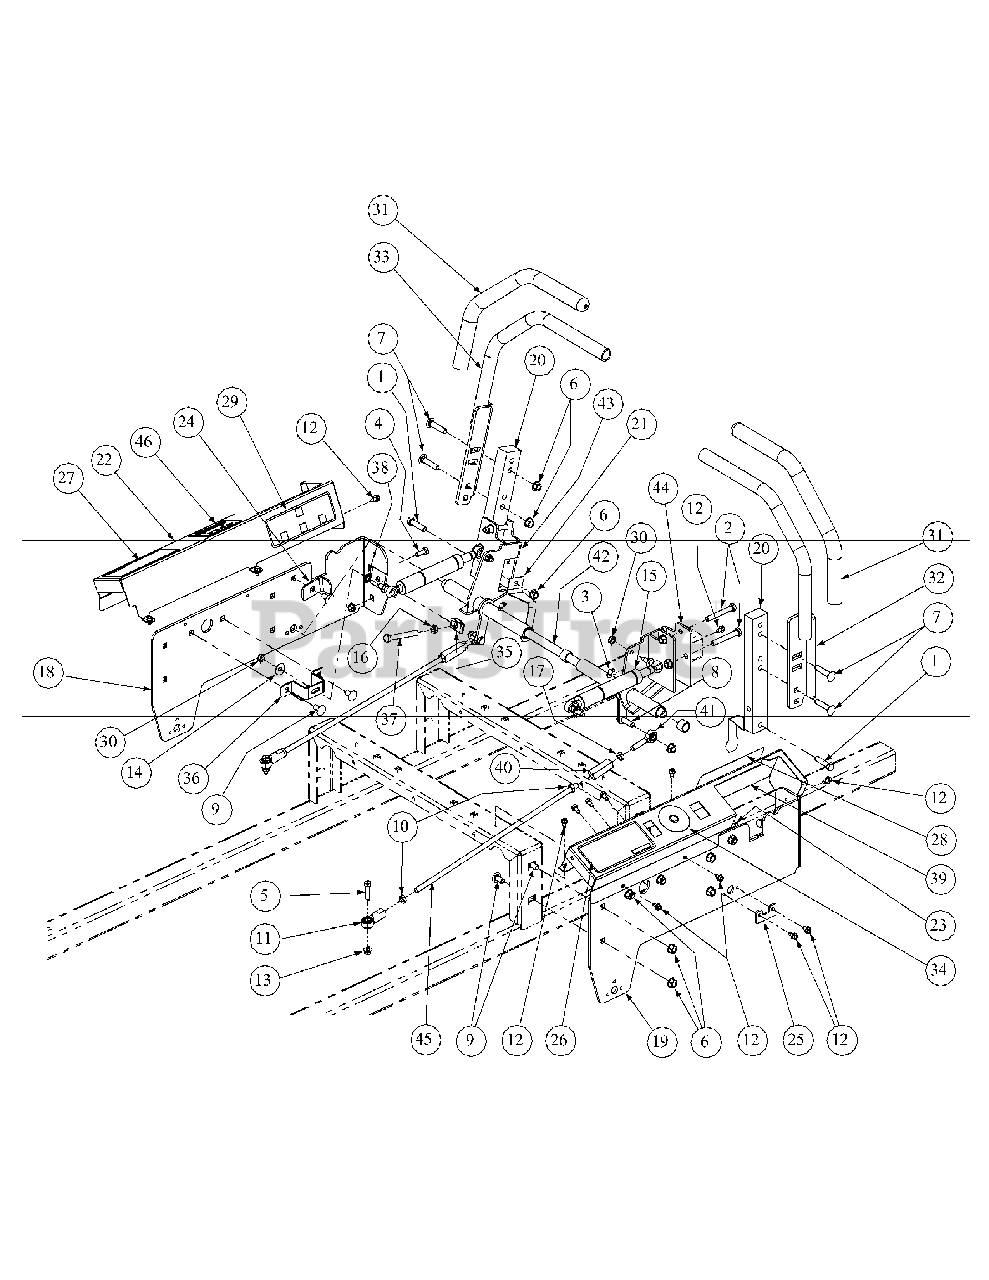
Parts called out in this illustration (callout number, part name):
1	HHCS, 3/8-16, 1.50
2	HHCS, 3/8-16, 2.50
3	Grease Fitting, 1/4-28, 90 degree
4	HHCS, 5/16-18 x 1.0
5	HHCS, 5/16-18 x 1.25
6	Hex Nut, 3/8-16, Lock Flange
7	Hex Carriage Screw, 3/8-16, 1.75
8	HHCS, 3/8-16 x 1.25
9	Carriage Bolt, 3/8-16 x .75
10	Hex Jam Nut, 3/8-24
11	B/Joint, 3/8-24, Right Hand Female
12	Screw, TT, 1/4-20, 0.5, Hex Index Washer
13	Nut, Lock, Hex Flange, 5/16-18
14	Belle Washer, .325 x .930 x .045
15	Cylinder Return to Neutral
16	Nut, 3/8-16, Jam
17	Nut, 3/8-24, Jam, LH Third
18	Side Panel, Control, Left
19	Side Panel, Control, Right
20	Mounting Handle
21	Lever, Safety Switch
22	Control Panel, LH
25	Holder Shaft, Park Brake
26	Decal , Right Hand Console
27	Decal, Left Hand Console
28	Decal Right Hand Control
29	Decal, Left Hand Control
30	Nut, Hex, Center Lock, M8
31	Grip, 1.0
32	Lapbar, Weldment, Right Handle
33	Lapbar, Weldment, Left Handle
34	Label, Ignition, 2.5 Diameter
35	U-Nut, 3/8-16, .75
36	Bracket Assembly, Mount Dampener
37	HHCS, 3/8-16, 3.00
38	External Washer, 3/8
39	Control Panel, RH
40	Turnbuckle
41	B/Joint, 3/8-24, Left Hand Female
42	Shaft Control Brake Steering
43	Bracket Assembly, Control LH Bearing
44	Bracket Assembly, Control RH Bearing
45	Control Rod
46	Plate, Light Indicator
